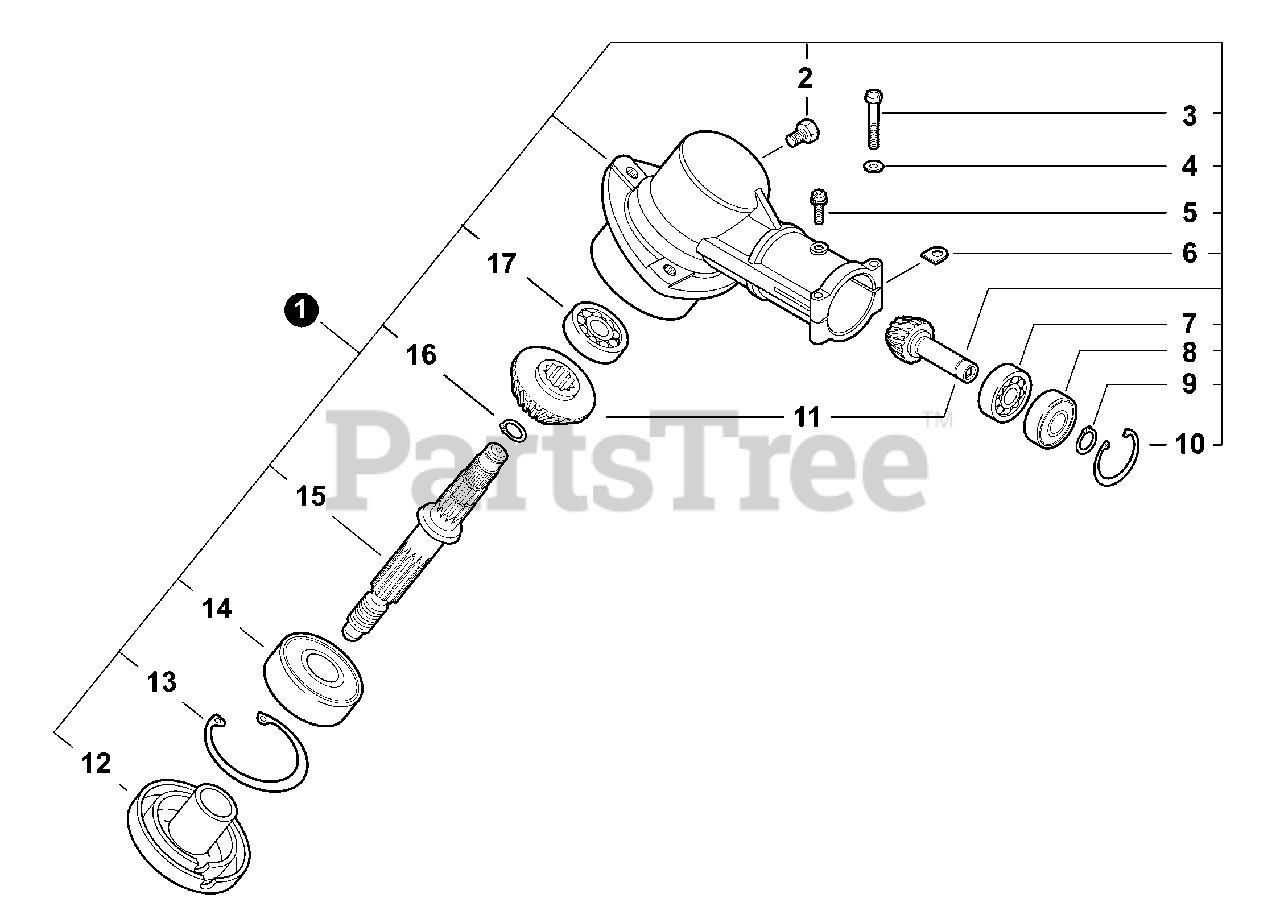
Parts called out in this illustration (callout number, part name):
1	GEAR CASE ASSY
2	BOLT M8×8
3	BOLT 5×35 SP
4	WASHER, FLAT 5.5×10×0.8
5	SCREW 5×12
7	BEARING, BALL 6900
8	BEARING, BALL 6900Z
9	RING, SNAP Ø10
10	RING, SNAP Ø22
11	GEAR SET
12	PLATE, ADAPTOR - UPPER
13	RING, SNAP Ø42
14	BEARING, BALL 6302
15	SHAFT, GEAR
16	RING, SNAP Ø12
17	BEARING, BALL 629
